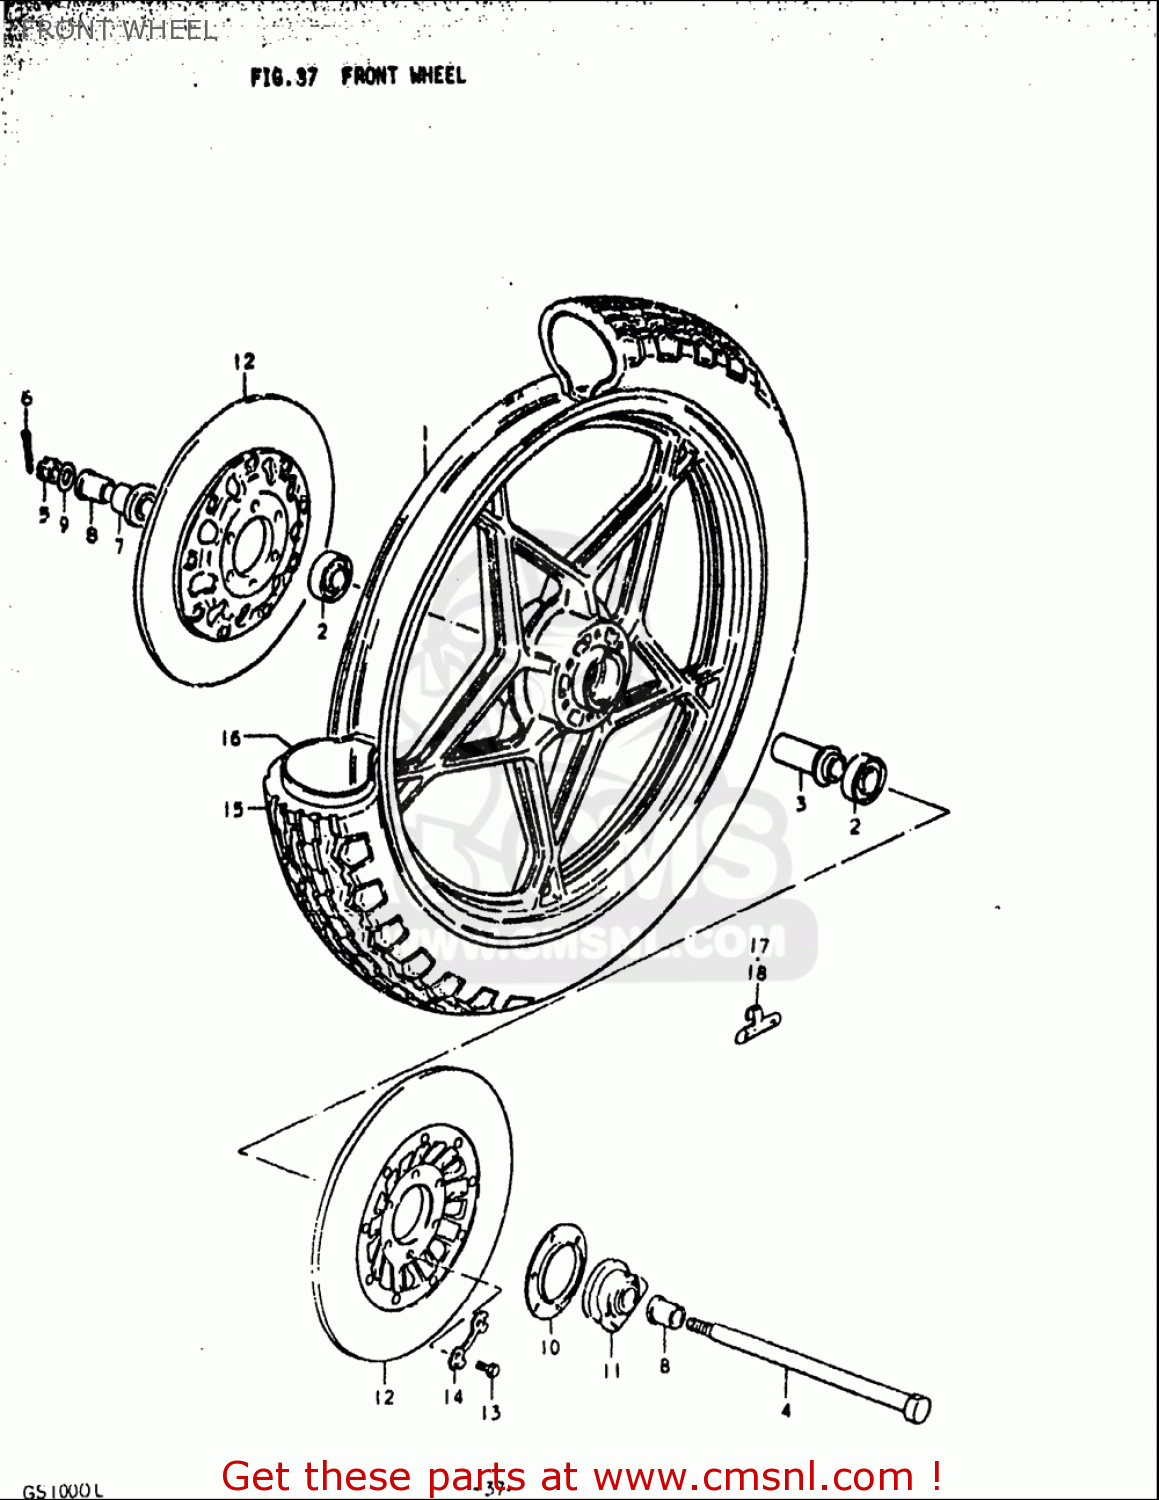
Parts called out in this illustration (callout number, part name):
1	WHEEL,FR(19XMT1.85)
3	SPACER,FR HUB BEARING
4	AXLE,FR
5	NUT 12MM
6	PIN
7	SPACER,FR AXLE,R
8	SPACER
9	WASHER(15.5X26X2.3)
11	BOX ASSY,SPEEDOMETER GEAR
13	BOLT(8X30)
14	WASHER
16	TUBE ASSEMBLY,WHEEL,INNER
17	BALANCER,WHEEL
